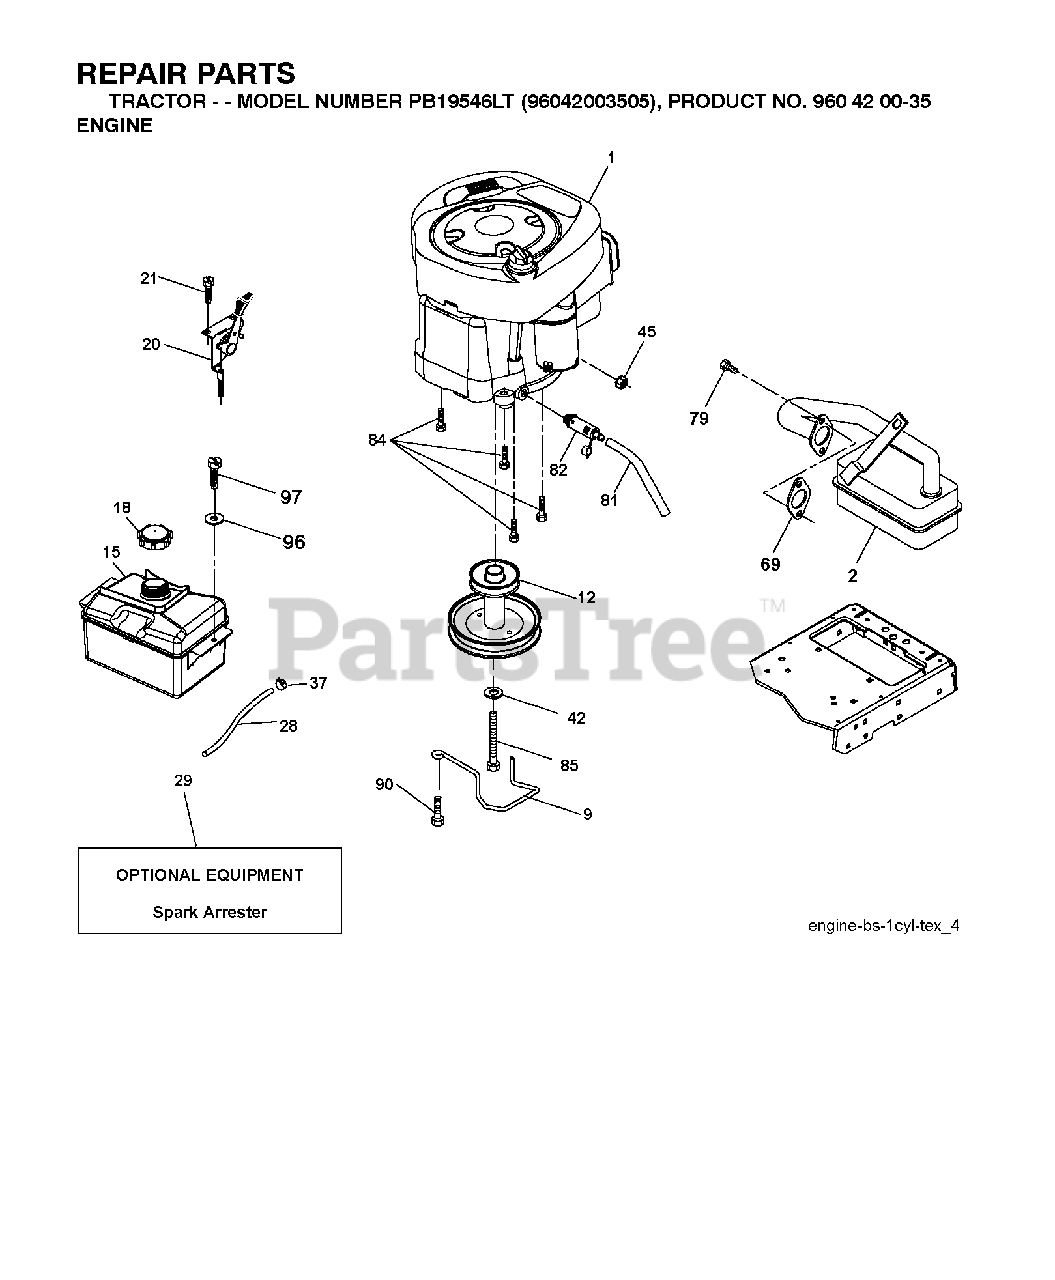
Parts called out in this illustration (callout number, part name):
1	Poulan TBD
2	MUFFLER.LT.BRIGGS.14HP.IC/OHV
9	KEEPER.BELT.ENGINE.3.25
12	PULLEY.ENGINE.5.0.PD
15	RP TANK FUEL FRT 1.5 GAL
18	CAP ASM.FUEL.2.25"FR.
21	SCREW.#10 X 0.750.BOS (2 2)
28	LINE.FUEL.20
29	KIT.SPARK ARRESTOR(392390 B&S)
37	HOSE CLAMP
42	LOCKWASHER
45	NUT
79	SCREW.SOCKET HD.5/16-1
84	SCREW.3/8-16
85	BOLT HEX 7/16-20X4-1/4"
90	SCREW 3/8-16X1
97	SCREW HEXWSHR 1/4-20X3/4
122	EXTENSION DRAIN OIL
